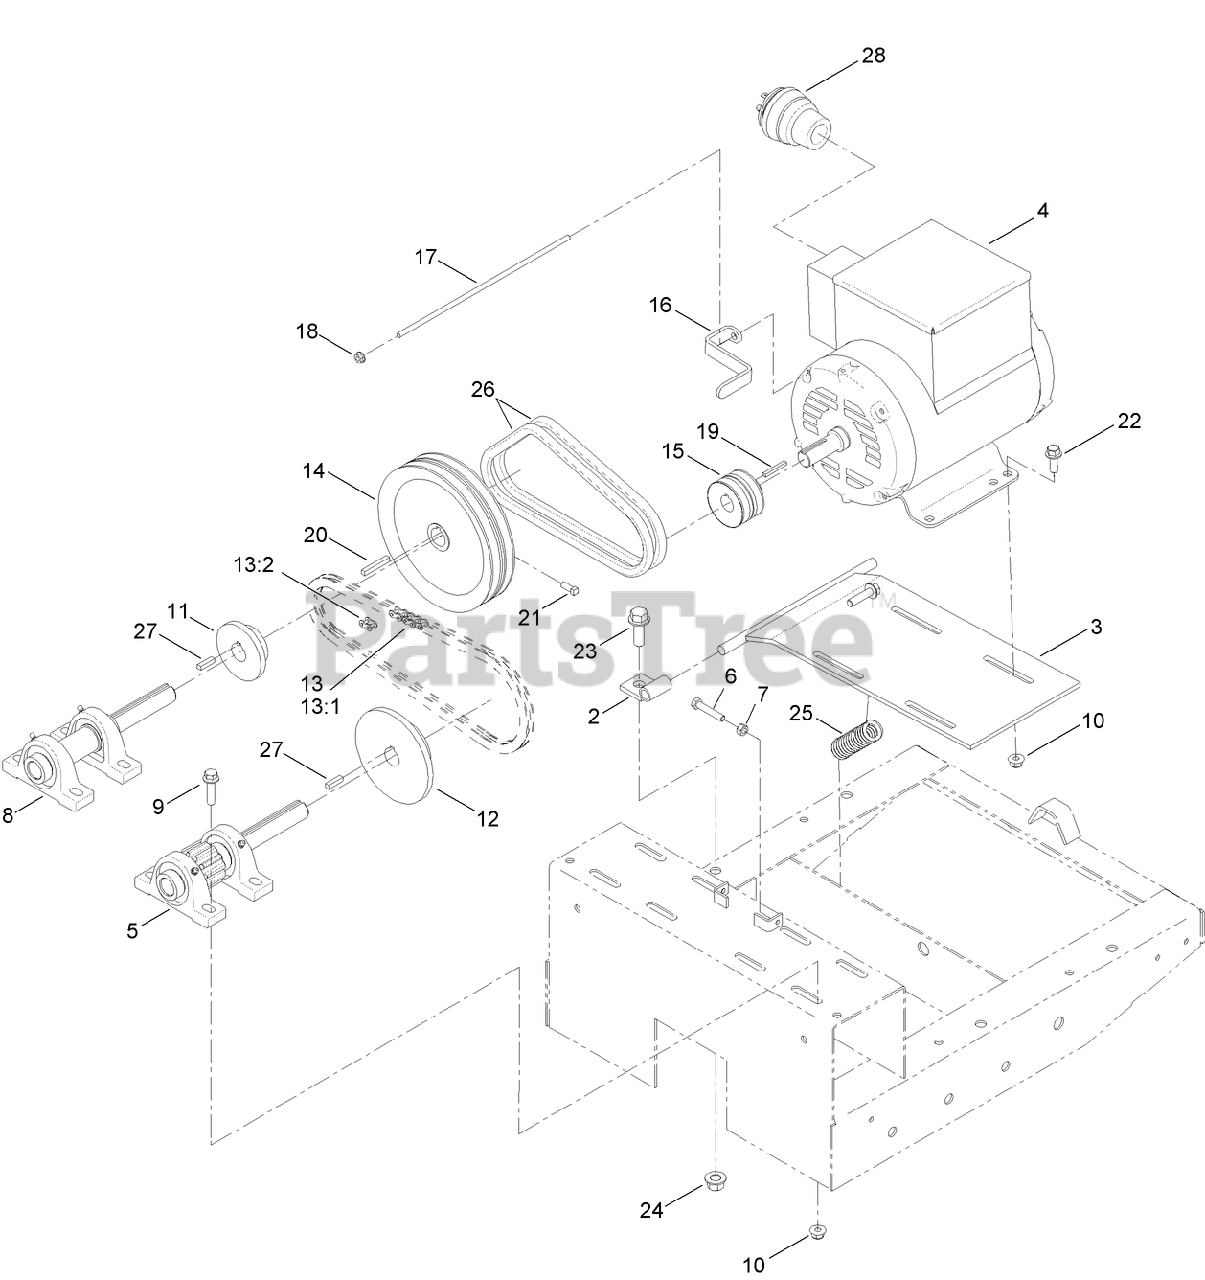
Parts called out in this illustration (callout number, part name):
2	MOUNT-MOTOR
3	BASE-MOTOR
4	MOTOR-ELECTRIC
5	PINION ASM
6	SCREW-HH
7	NUT-HEX
8	IDLER ASM
9	SCREW-HHF
10	NUT-HF, NI
11	SPROCKET
12	SPROCKET
13	CHAIN SET
13:1	CHAIN
13:2	LINK-CONNECTING, NO. 50
14	SHEAVE
15	SHEAVE
16	GUIDE-BELT
17	ROD-THREADED
18	NUT-HF
19	KEY-SQUARE
20	KEY-SQUARE
21	SCREW-SET, SQH
22	SCREW-HHF
23	SCREW-HHF
24	NUT-LOCK
25	SPRING
26	BELT-V
